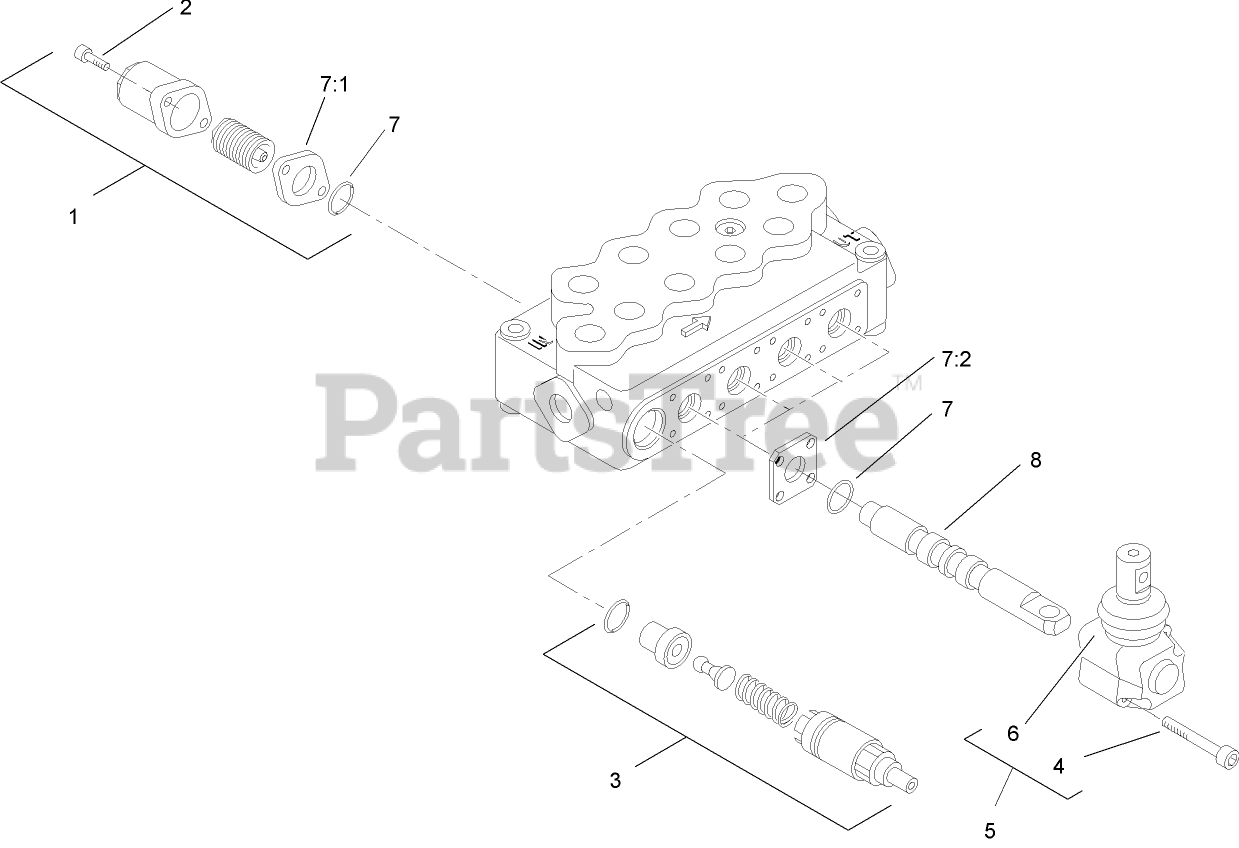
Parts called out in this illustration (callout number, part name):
1	HIGH FORCE SPRING KIT
1	STANDARD SPRING KIT
2	SCREW-CAP, END
3	VALVE-RELIEF
5	OPERATOR ASM
7	SEAL KIT
7:1	GASKET
7:2	GASKET
8	SPOOL-VALVE
